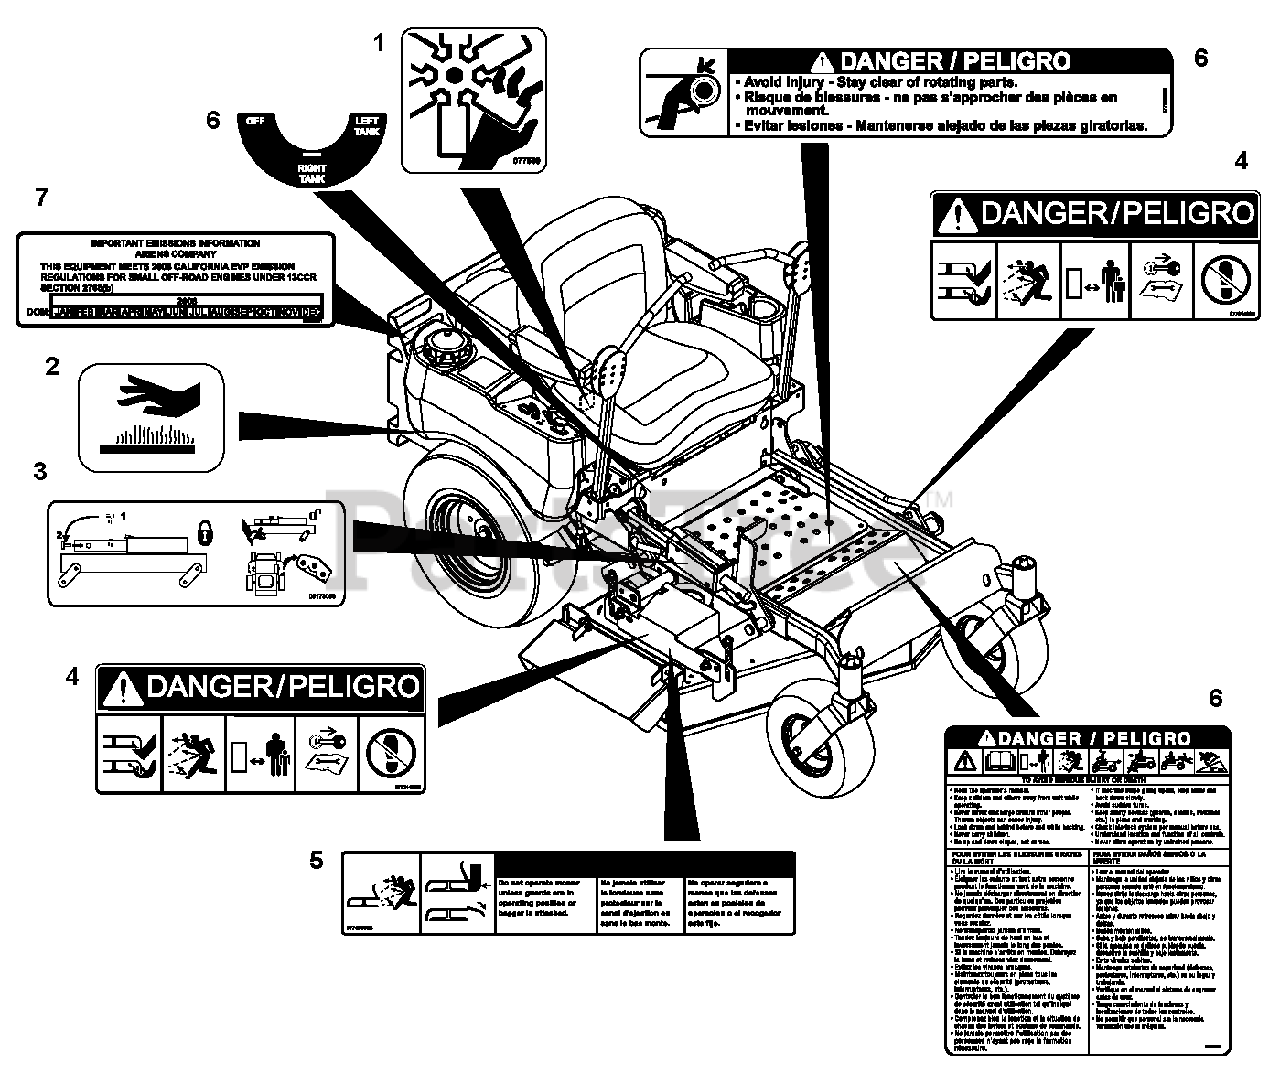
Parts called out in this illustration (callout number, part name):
1	Decal, Danger Fan
2	Decal, Hot Surface
3	Decal, Deck Service
4	Decal, Mower Pan Head Danger
5	Decal, Warning
6	Set, Decal Common Danger/Fuel
7	Decal, CARB Label
